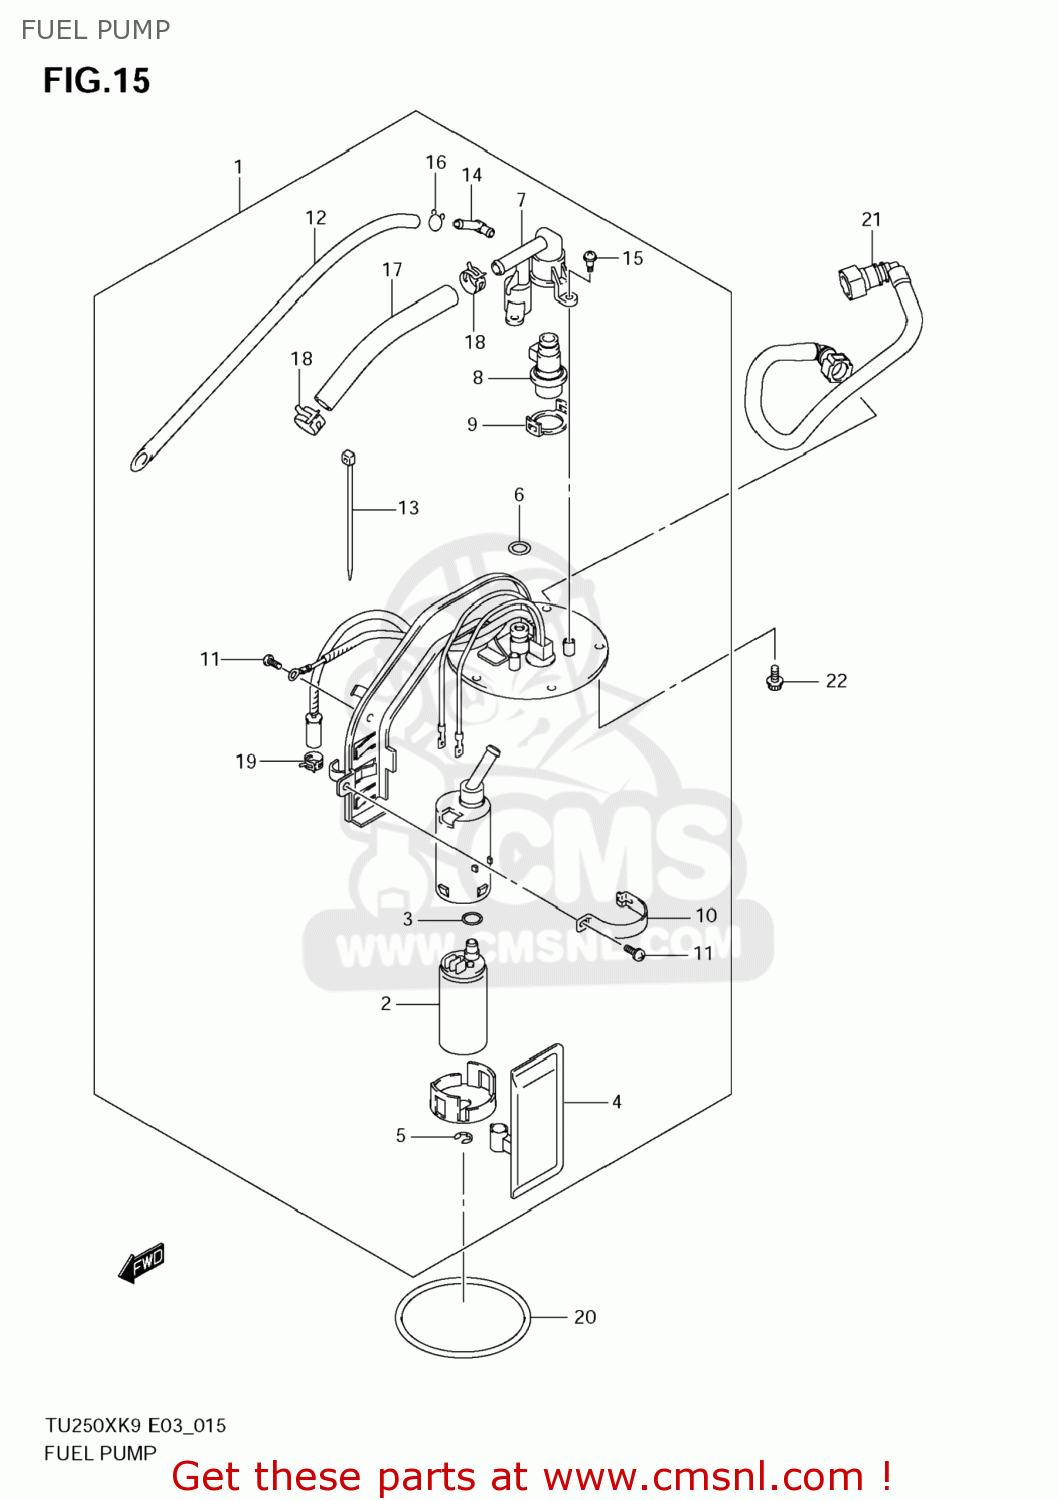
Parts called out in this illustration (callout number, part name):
1	PUMP ASSY,FUEL
2	PUMP,FUEL
3	O RING
4	FILTER
5	PLATE
6	O RING
7	ADAPTER
8	REGULATOR,PRESSURE
9	CLIP
10	BAND
11	SCREW
12	HOSE
13	CLAMP
14	JOINT
15	SCREW
16	CLIP
17	HOSE
18	CLIP
19	CLAMP
20	O RING,FUEL PUMP
21	HOSE,FUEL
22	BOLT
